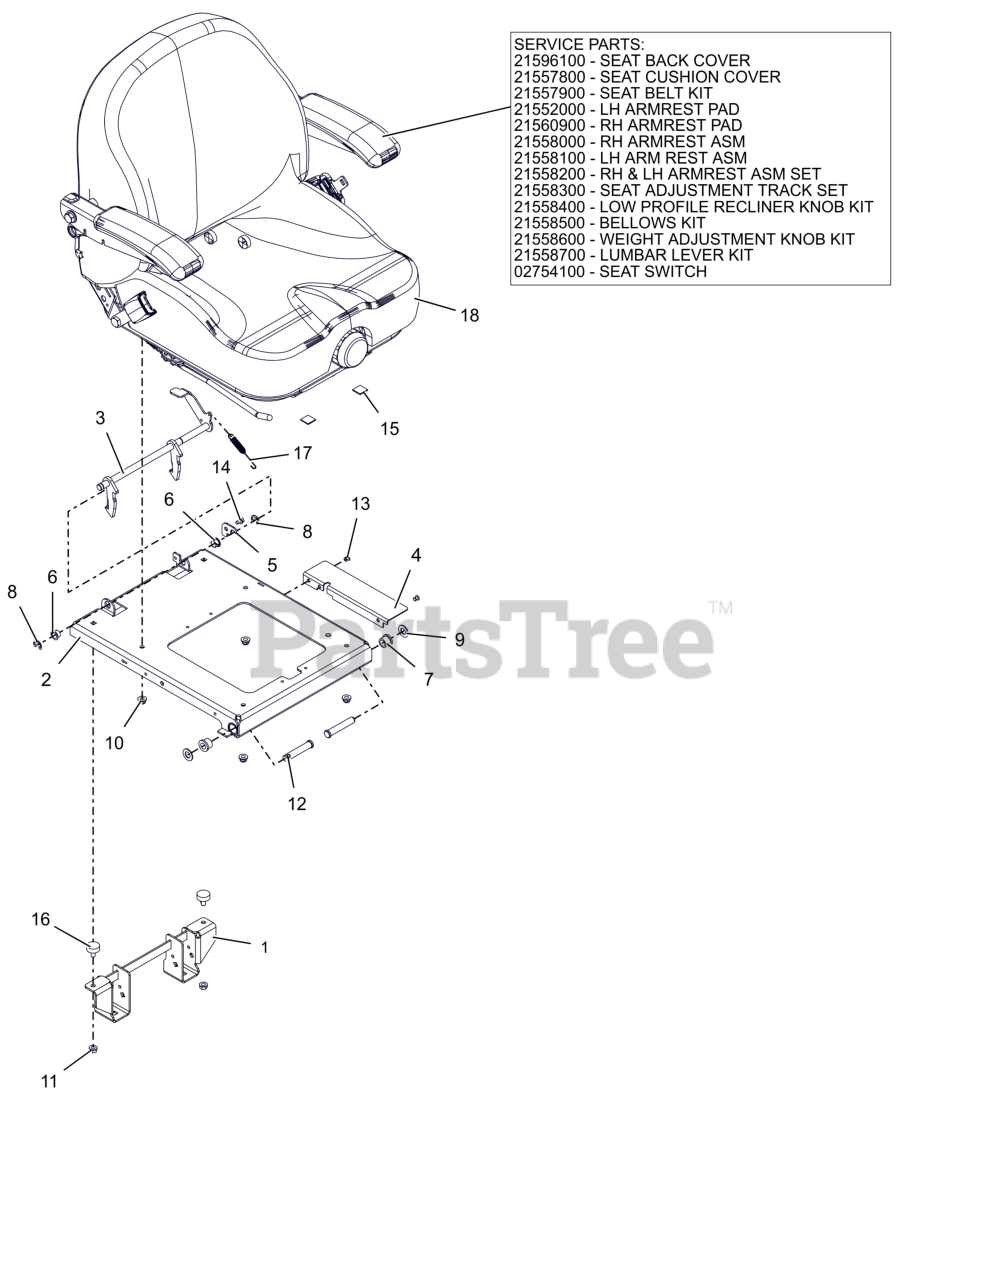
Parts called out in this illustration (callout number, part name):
1	WLDMT- LATCH RECEIVER
2	WLDMT- MECH. SUSP. SEAT PLATE
3	WLDMT- SUSP. SEAT LATCH
4	GUARD- SEAT PLATE
5	BRKT- ROD KEEPER
6	BUSHING, POLYLINER-.50 SPLIT
7	BSHG, FLG .516X.750X.625X.937
8	RG-RTNG-EXT .500X.042 (E)
9	WSHR, FLT .531X1.00X.063 ZCC
10	NUT,LK-NYL-FLG .31-18 G5ZC120
11	NUT,SPNLK-FLG .31-18 G5 ZCC
12	PIN-CLIC .50X2.70X2.31 -ZCC
13	RVT-POP .187x.250 (#64) BLK
14	SCR,TAP .25-20X.375 HWH TR ZCC
16	BUMPER, RUBBER
17	SG-TENS .043X.44X3.31 WLD 5.8
18	SEAT-MECH. SUSP. 18"
18	COVER SEAT BACK
18	SEAT CUSHION COVER
18	SEAT BELT KIT
18	PAD, ARMREST
18	PAD, ARMREST (HARD)
18	RH ARMREST ASM
18	LH ARMREST ASM
18	RH & LH ARMREST ASM SET
18	SEAT ADJUSTMENT
18	KIT, LOW PROFILE RECLINER KNOB
18	BELLOWS KIT
18	WEIGHT ADJUSTMENT KNOB KIT
18	LUMBAR LEVER KIT
18	SWITCH- SNAP MTG N.O.
